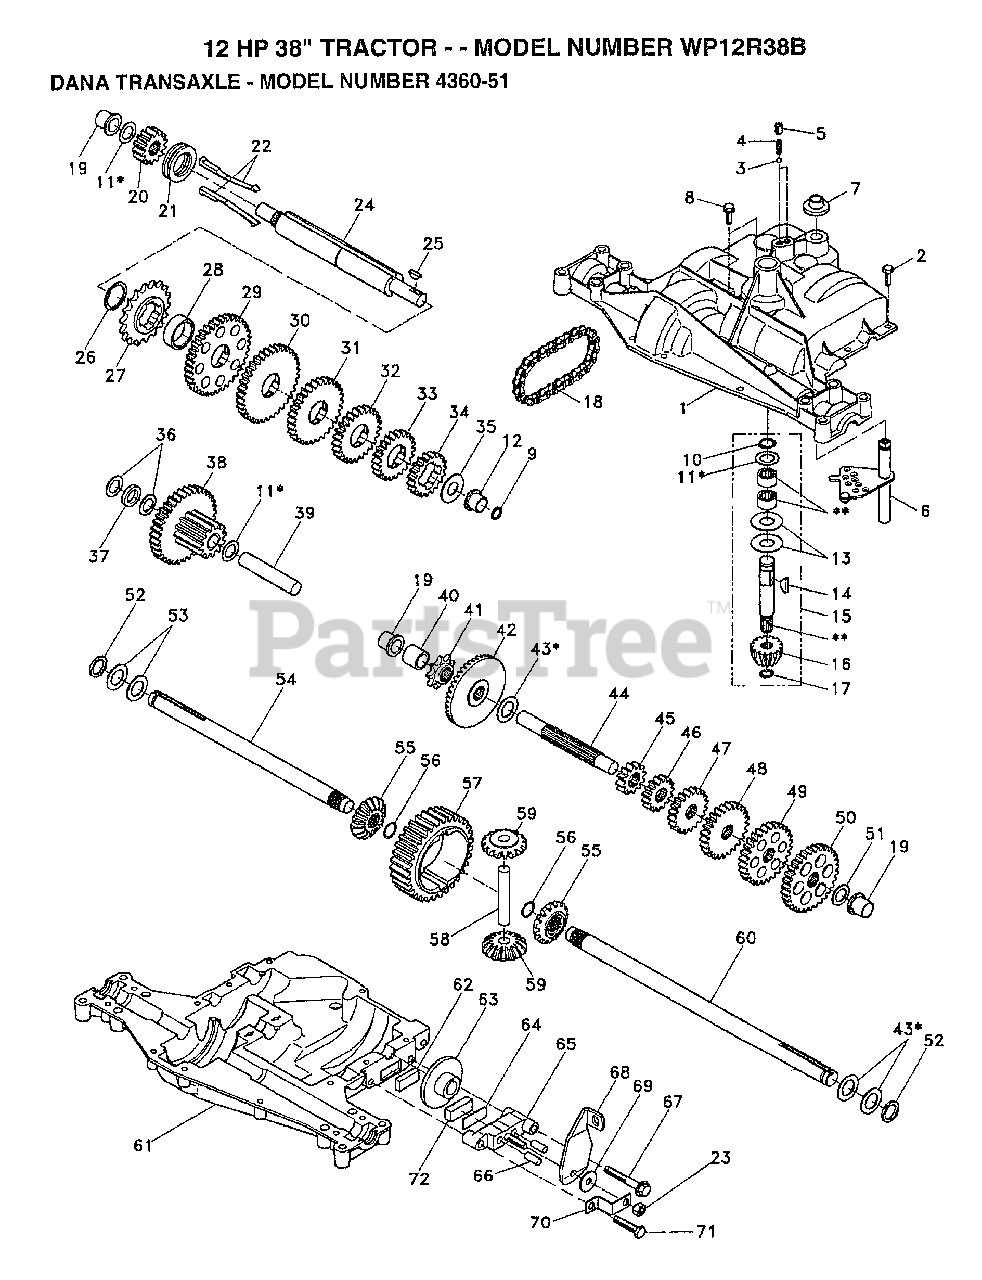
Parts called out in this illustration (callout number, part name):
4	"SPRING, DETENT LT"
5	"SCREW, SET LT"
6	KIT SHIFTER ASM
7	SHIFTER BOOT
8	SCREW TAP W/SEAL
9	SQUARE RING
10	RETAINING RING LT
11	ASM KIT SHIM 4689
12	"FLANGE, BEARING"
13	WASHER T
14	WOODRUFF KEY
15	AS KIT INPUT SHFT
16	PINION 14T T
17	"RING,RETAINING LT"
18	"CHAIN,24 PTCH LT"
19	BEARING.FLNG.5510
20	GEAR SPUR 14T
21	COLLAR CLUTCH
22	ASM KIT CLTCH KEY
23	NUT.LOCK.5/16-24
24	SHAFT INTERM
25	WOODRUFF KEY
26	"RING,RETAINING LT"
27	SPROCKET 18T T
28	SPACER YT
29	KIT.GEAR.12/37TH
32	GEAR 25T LT
33	GEAR SPUR 22 TT
34	SPUR GEAR 19T
35	"WASHER, PLAIN LT"
36	WASHER 025
37	SPACER
38	ASSM GEAR COMB
39	SHAFT IDLER
40	SPACER T
41	SPROCKET 9T LT
43	ASM KIT SHIM
44	SHAFT T
48	"GEAR, SPUR 25T LT"
49	GEAR 28T T
50	"GEAR, SPUR 31T LT"
51	WASHER 060
52	NEOPRENE WASHER
53	WASHER 031
55	GEAR 15T T
56	"RING,RETAINING LT"
58	SHAFT T
59	GEAR 1ST T
62	PUCK T
63	BRAKE DISC. T
64	SPACER LT
66	PIN T
69	WASHER LT
71	"SCREW, TAPPING LT"
72	PUCK T
